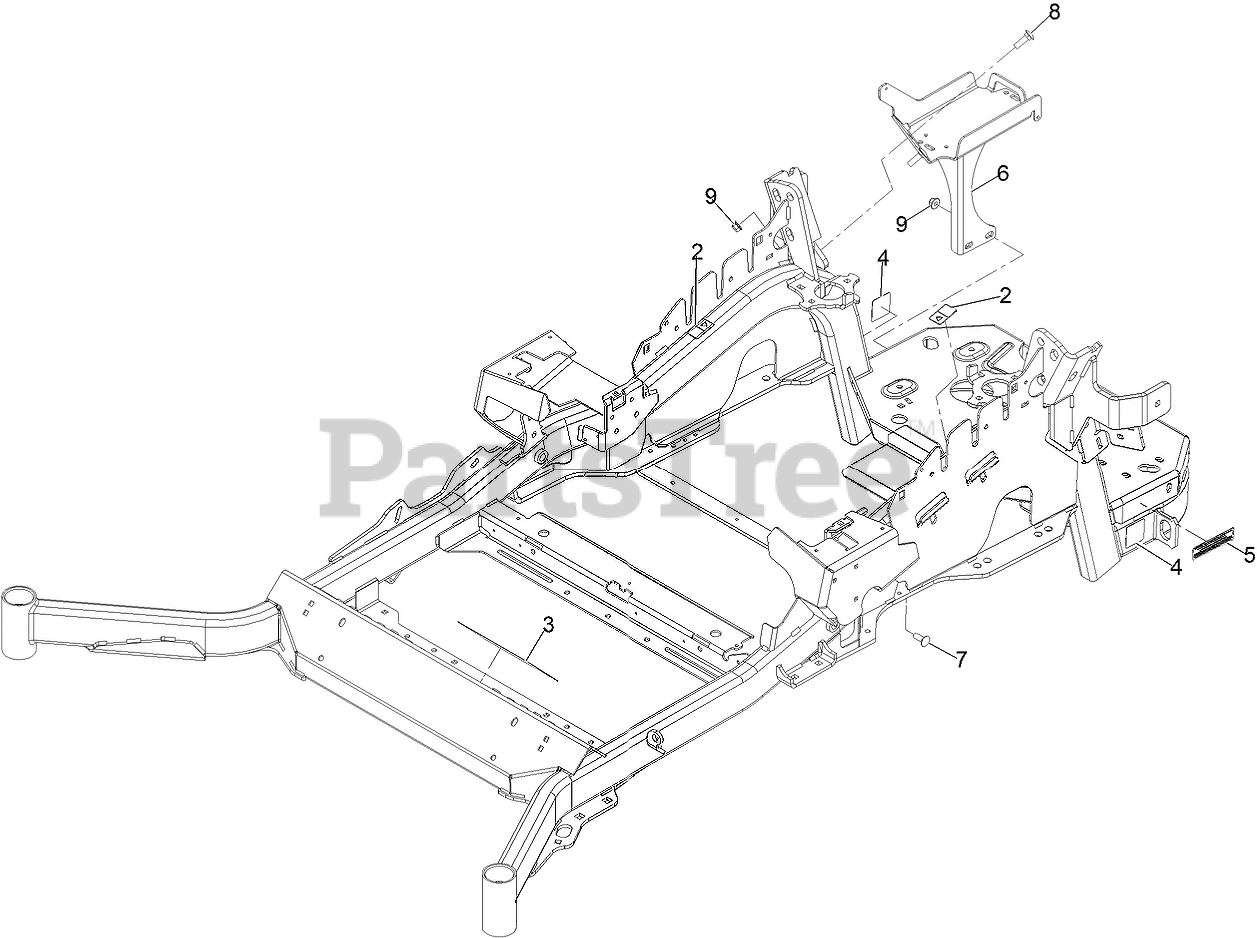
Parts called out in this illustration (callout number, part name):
2	DECAL-WARNING
3	DECAL-DANGER
4	DECAL-HAZARD, PINCHED FINGER
5	DECAL-ARRESTOR, SPARK
6	BATTERY MOUNT ASM
7	SCREW-CARR
8	BOLT-CARR
9	NUT-HF, NI
